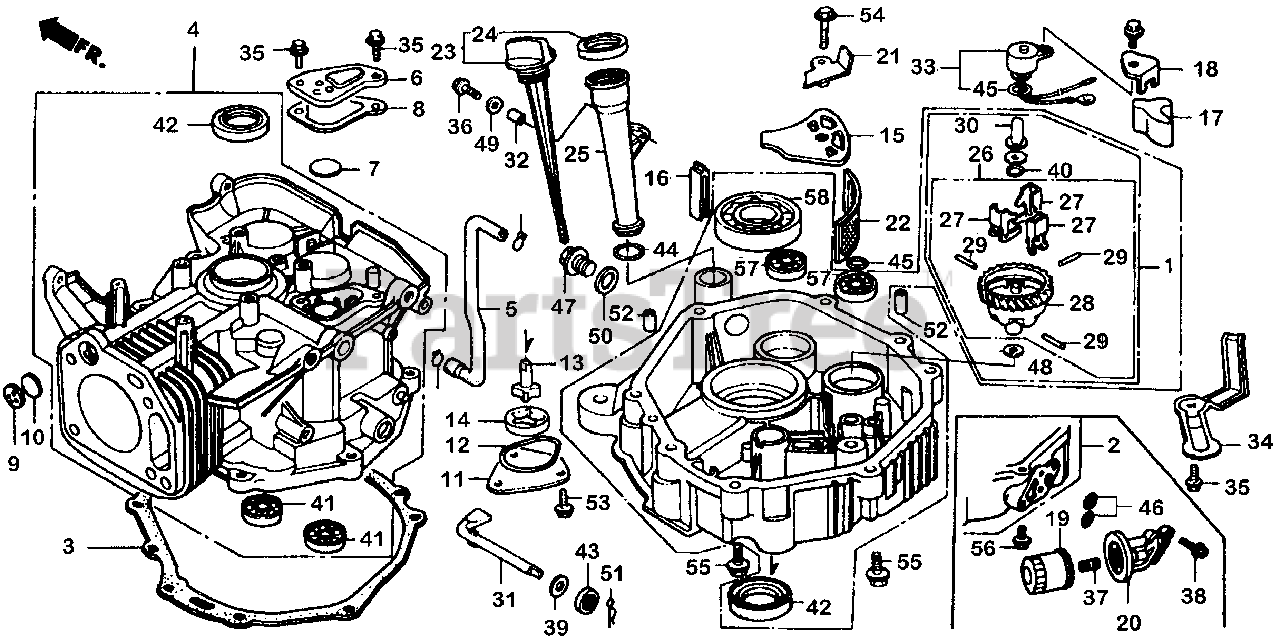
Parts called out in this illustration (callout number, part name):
1	GOVERNOR KIT
2	PAN ASSY., OIL
3	GASKET, OIL PAN
4	CYLINDER ASSY.
5	TUBE, BREATHER
6	CAP, BREATHER CHAMBER
7	VALVE, BREATHER
8	GASKET, BREATHER CAP
9	PLATE, ONE-WAY VALVE
10	VALVE, ONE-WAY
11	COVER, OIL PUMP
12	O-RING, PUMP COVER
13	ROTOR (INNER)
14	ROTOR, OIL PUMP (OUTER)
15	PLATE, OIL FILTER
16	RUBBER, OIL RETURN
17	STOPPER, OIL
18	PLATE, OIL STOPPER
19	FILTER, OIL (FILTECH TOYO ROKI) (SOLD INDIVIDUALLY)
19	FILTER, OIL (TOYO ROKI) (SOLD IN MULTIPLES OF 30)
19	FILTER, OIL (ALLIED SIGNAL USA) (SOLD IN MULTIPLES OF 30)
19	FILTER, OIL (SOLD IN MULTIPLES OF 30)
19	FILTER, OIL (TOYO ROKI) (SOLD INDIVIDUALLY)
19	FILTER, OIL (SOLD INDIVIDUALLY)
20	BASE, OIL FILTER
21	PLATE, SUCTION
22	SCREEN, OIL FILTER
23	CAP ASSY., OIL FILLER
24	GASKET, OIL FILLER CAP
25	EXTENSION, OIL FILLER
26	GOVERNOR ASSY.
27	WEIGHT, GOVERNOR
28	HOLDER, GOVERNOR WEIGHT
29	PIN, GOVERNOR WEIGHT
30	SLIDER, GOVERNOR
31	SHAFT, GOVERNOR ARM
32	COLLAR, EXTENSION
33	SWITCH, OIL LEVEL
34	PROTECTOR, SWITCH
35	BOLT, FLANGE (6X12) (CT200)
36	BOLT, FLANGE (6X35) (CT200)
37	HOLDER, OIL FILTER
38	BOLT, FLANGE (6X25) (CT200)
39	WASHER, THRUST (8.1MM)
40	CLIP, GOVERNOR HOLDER
41	BEARING, RADIAL BALL (6202)
42	OIL SEAL (35X52X8)
43	OIL SEAL (8X14X5)
44	O-RING (22.1X2.2)
45	O-RING (11.8X2.4)
46	O-RING (11X1.9) (NOK)
47	BOLT, DRAIN PLUG (20MM)
48	WASHER, PLAIN (6MM)
49	WASHER, PLAIN (6MM)
50	WASHER, DRAIN PLUG (20MM)
51	PIN, LOCK (8MM)
52	PIN, DOWEL (8X12)
53	BOLT, FLANGE (6X12)
54	BOLT, FLANGE (6X25)
55	BOLT, FLANGE (8X40)
56	BOLT, FLANGE (8X60)
57	BEARING, RADIAL BALL (6202)
58	BEARING, RADIAL BALL (6207)
